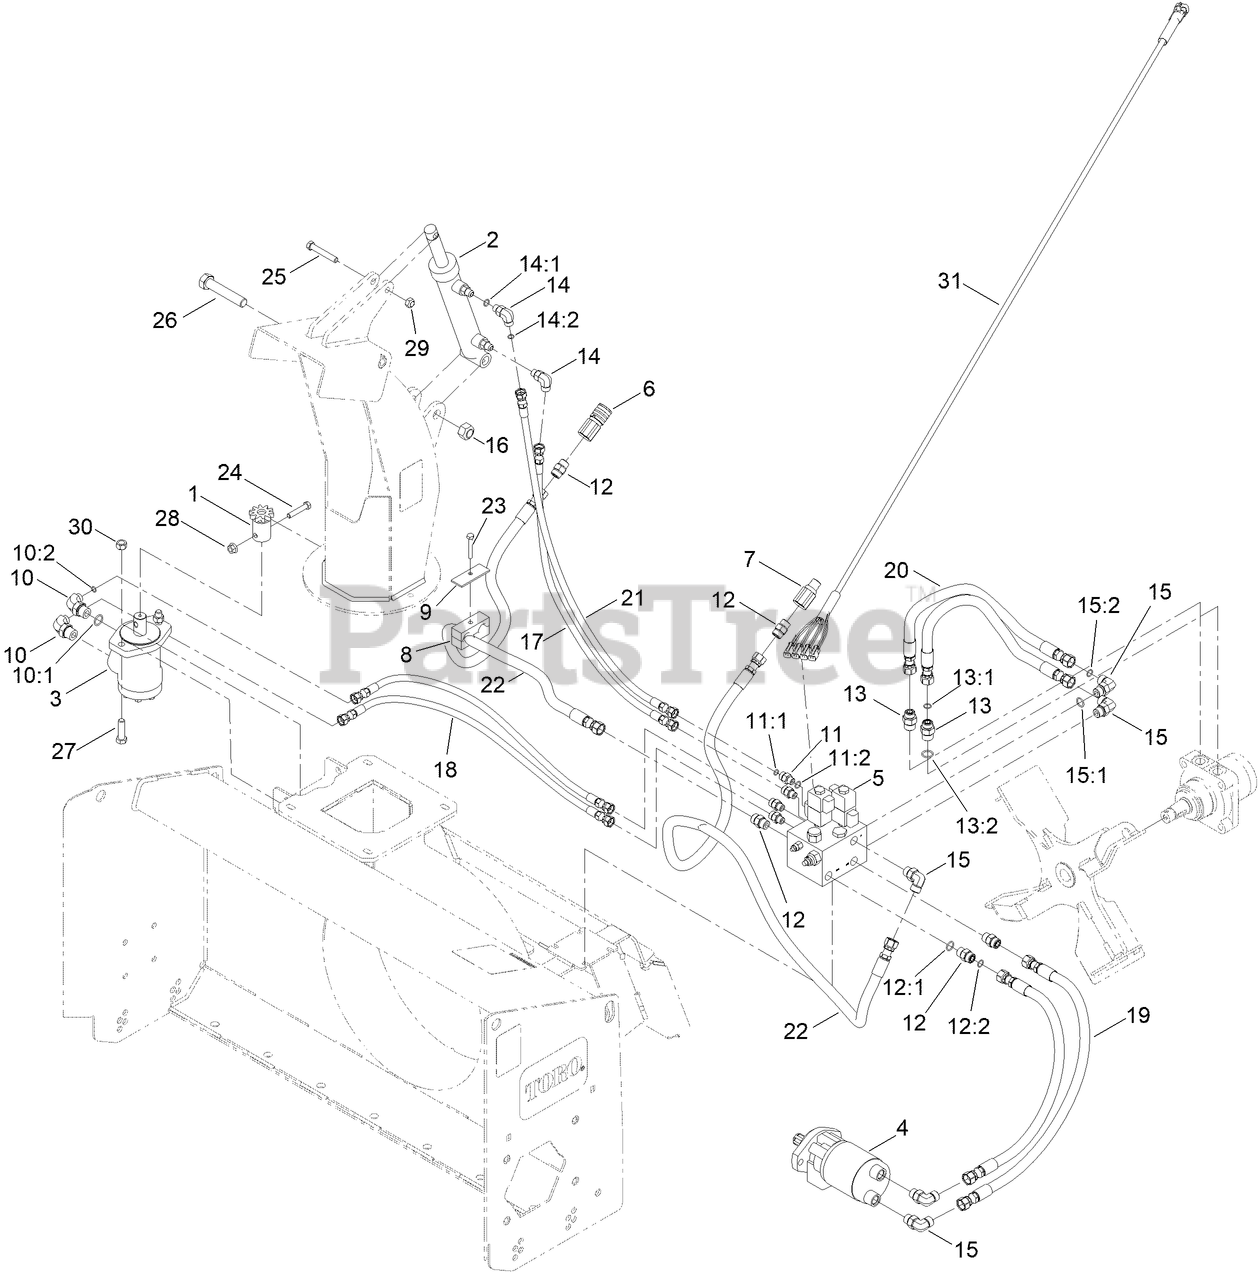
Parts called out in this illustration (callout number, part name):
2	CYLINDER - ASM
3	MOTOR-CHUTE
4	MOTOR-PADDLE ASM
5	VALVE ASM
6	FITTING-QUICK COUPLING
7	FITTING-QUICK COUPLING
9	BRACKET-CLAMP
10	FITTING-ELBOW 90
10:1	O-RING
10:2	O-RING
11	FITTING-STRAIGHT
11:1	O-RING
11:2	O-RING
12	FITTING-STRAIGHT
12:1	O-RING
12:2	O-RING
13	FITTING-STRAIGHT
13:1	O-RING
13:2	O-RING
14	FITTING-ELBOW, 90 DEG
14:1	O-RING
14:2	O-RING
15	FITTING-ELBOW, 90 DEG
15:1	O-RING
15:2	O-RING
16	NUT-LOCK
17	HOSE ASM - HYD
18	HOSE ASM - HYD
19	HOSE ASM - HYD
20	HOSE ASM - HYD
21	HOSE ASM - HYD
22	HOSE ASM - HYD
23	SCREW-HH
24	SCREW-HH
25	SCREW-HH
26	SCREW-HH
27	SCREW-HH
28	NUT-LOCK, FLANGE
29	NUT-HEX
30	NUT-HEX
31	HARNESS-WIRE
